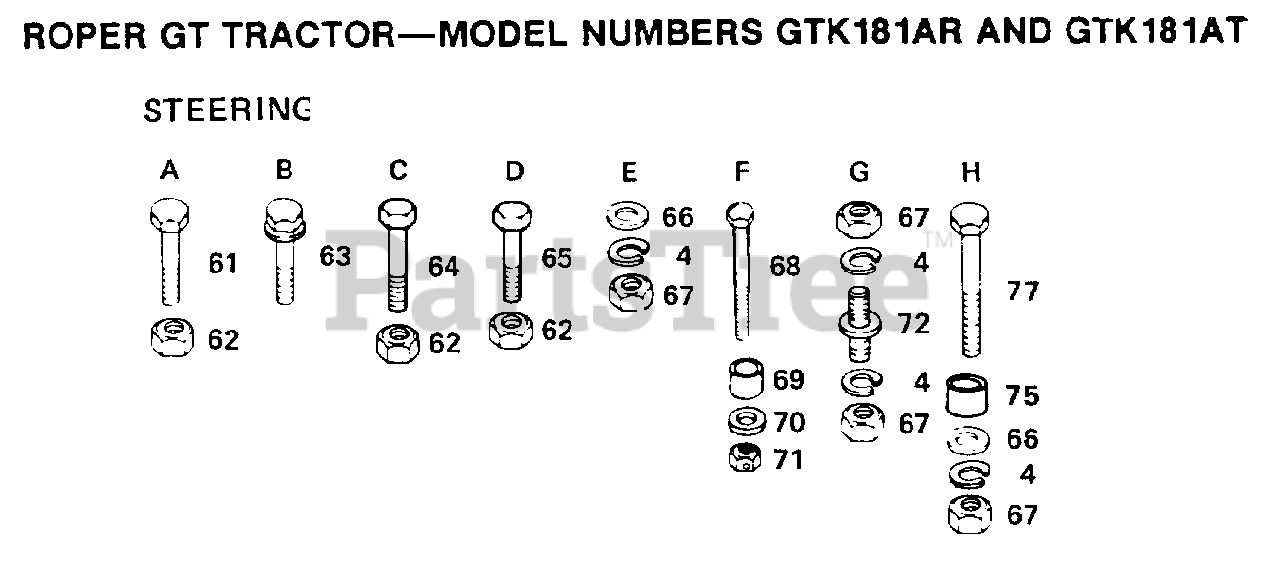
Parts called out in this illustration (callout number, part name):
4	LOCKWASHER
63	SCREW
64	BOLT
65	BOLT
66	WASHER
67	NUT.HEX.3/8-16UNC
69	BUSHING LT
70	WASHER
75	SPLIT SPACER YTV
77	BOLT
